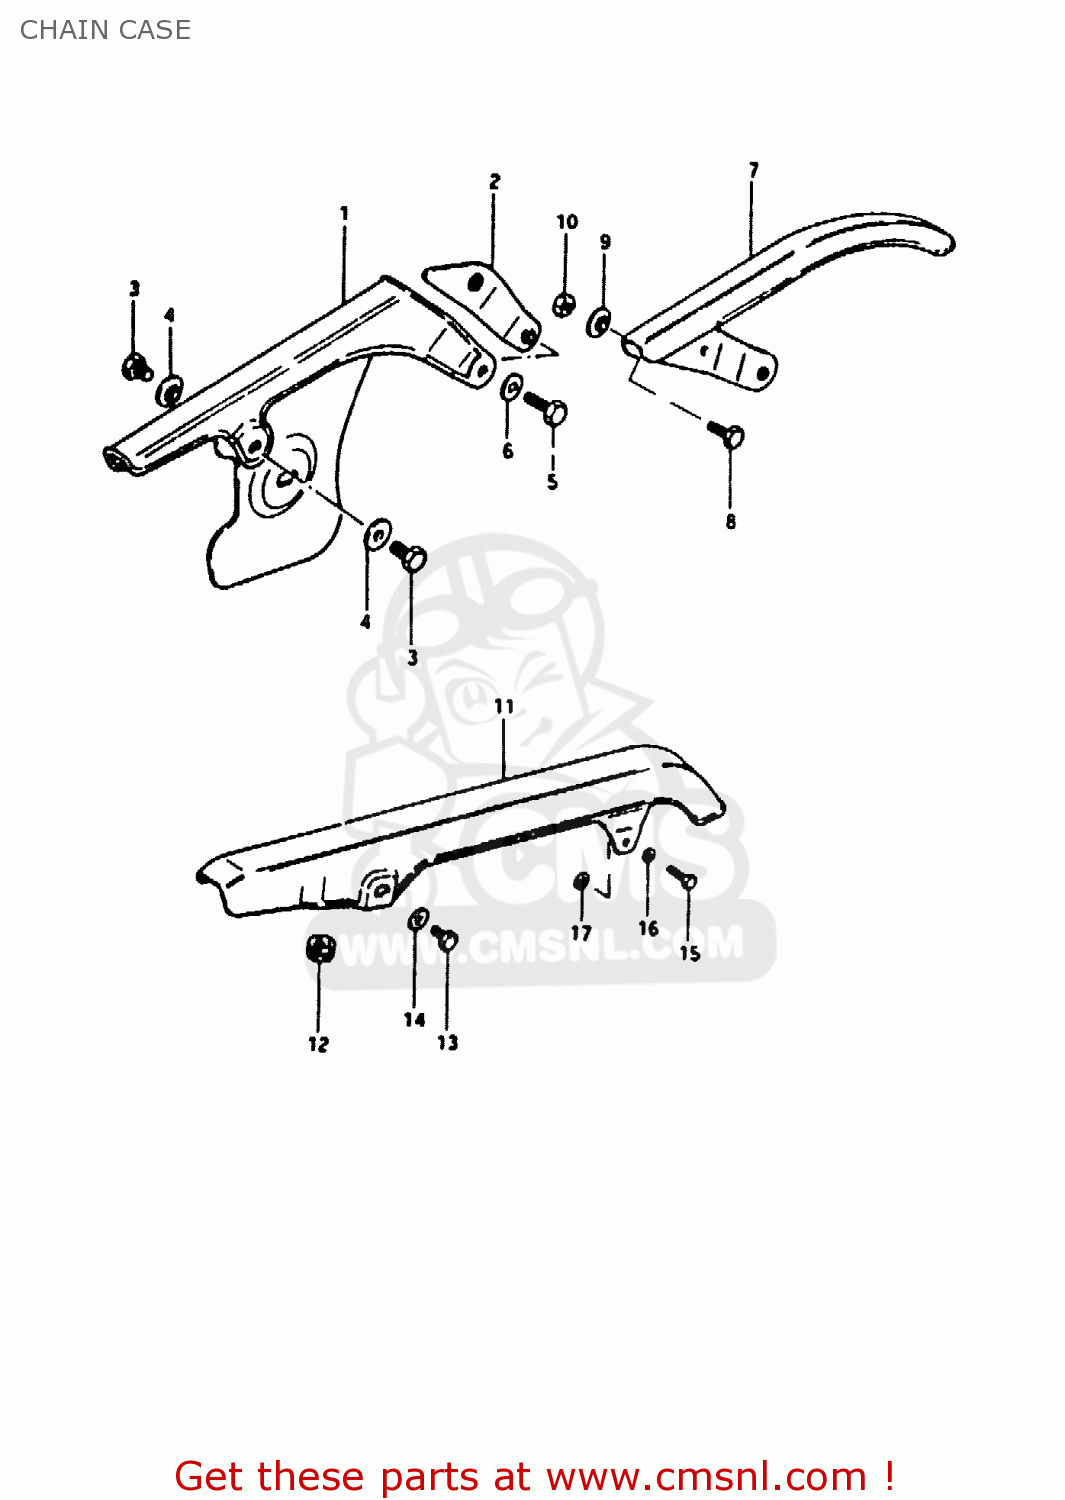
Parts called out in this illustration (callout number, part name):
1	CASE,CHAIN
2	REINFORCEMENT,CHAIN CASE
3	BOLT(6X8)
4	WASHER
5	BOLT, UPPER
6	WASHER
